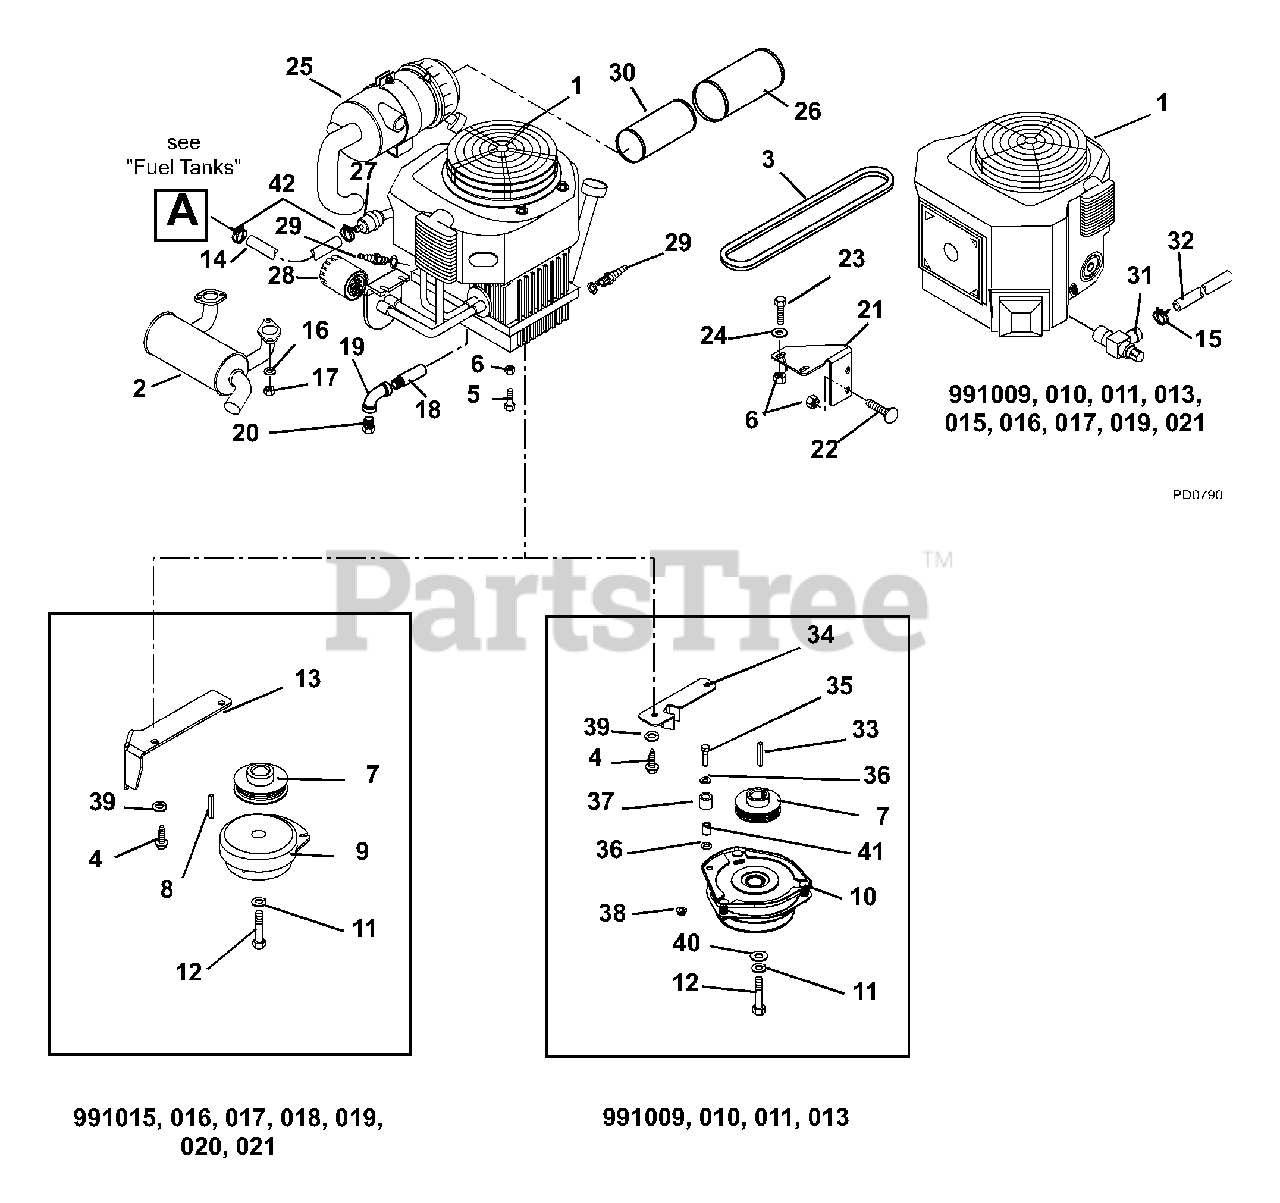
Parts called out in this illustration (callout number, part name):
1	Engine, Kohler, 25hp
1	Engine, Kawasaki 25hp
1	Engine, Kawasaki 21HP
1	Engine, Kawasaki 23HP
2	Muffler, Kohler
2	Muffler, Kawasaki
3	V-Belt HA 52 x .535 G48667
4	Bolt, 38-16X1 6-LOBE PH TRX YZ
5	Bolt, Hex .31-18 x 1.50 Grade 5
6	Nut, Locking Top Flange .31-18
7	Pulley-V 4.00 x 1.125 with Key 1.42 Height
7	Sheave, Engine 4.581 x 1.127 with Key
8	Key, Square .25 x .625 x .25 SAE 8630 OR SAE 1035
9	Clutch, Electric
10	Clutch, Electric
11	Washer, Locking .44 x .109
12	Bolt, Hex .44-20 x 2.25 Grade 5
13	Clutch Stop
14	Gas Line, Bulk .25 ID
15	Hose, Clamp .88
16	Washer, Lock .31 x .078 Regular
17	Nut, Hex M8-1.25
18	Nipple
19	Elbow .375-18
20	Pipe Plug
21	Bracket, Oil Filter Mounting-Kohler
22	Bolt, Round Head Square Neck .31-18 x .62
23	Bolt, Hex .31-18 x 1.00 Grade 5
24	Washer, Flat Steel .38 x .875 x .083
25	Assembly, Air Cleaner
26	Filter, Outer Element
27	Fuel Filter, Kohler
27	Fuel Filter, Kawasaki
28	Oil Filter, Kohler
28	Oil Filter, Kawasaki
29	Spark Plug, Kohler
29	Spark Plug, Kawasaki
30	Filter, Inner Element
31	Drain, 1/2" Oil
32	Tube, Oil Drain
33	Key-Square .25 x 3.50 x .25 SAE
34	Anchor Clutch
35	Bolt-Hex .38-16 x 1.50 Grade 5
36	Washer-Flat-Steel .406 x .812 x .065
37	Bumper,Rubber .62 x 1.0 x .88 LG
38	Nut-Locking-Top-Flange .38-16
39	Washer, Lock .31 x .078
40	Washer, Flat Steel .469 x 2 x .25
41	Bushing, .407 x .625 x .813
42	Clamp, Hose Wire .490/.510 x .116
